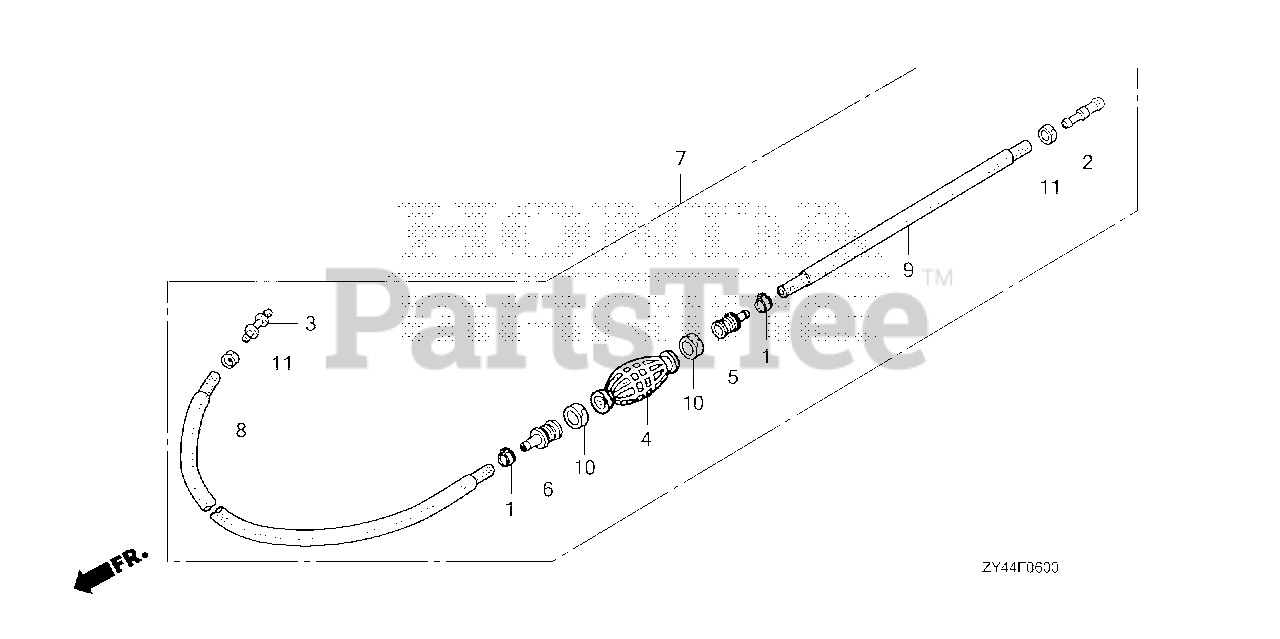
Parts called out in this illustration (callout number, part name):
1	CLAMP, FUEL TUBE
1	CLAMP, FUEL TUBE (14.0)
2	JOINT, FUEL TUBE
3	JOINT, FUEL TUBE
4	BULB, PRIMER
5	VALVE, IN.
6	VALVE, OUTLET
7	TUBE ASSY., FUEL TANK (JOINT TYPE)(FKM)
8	TUBE, FUEL LONG (7.3X2000)
9	TUBE, FUEL SHORT
9	TUBE, FUEL SHORT (7.3X500)
10	BAND, TUBE CLIP (20MM)
11	BAND, TUBE CLIP (12.5MM)
